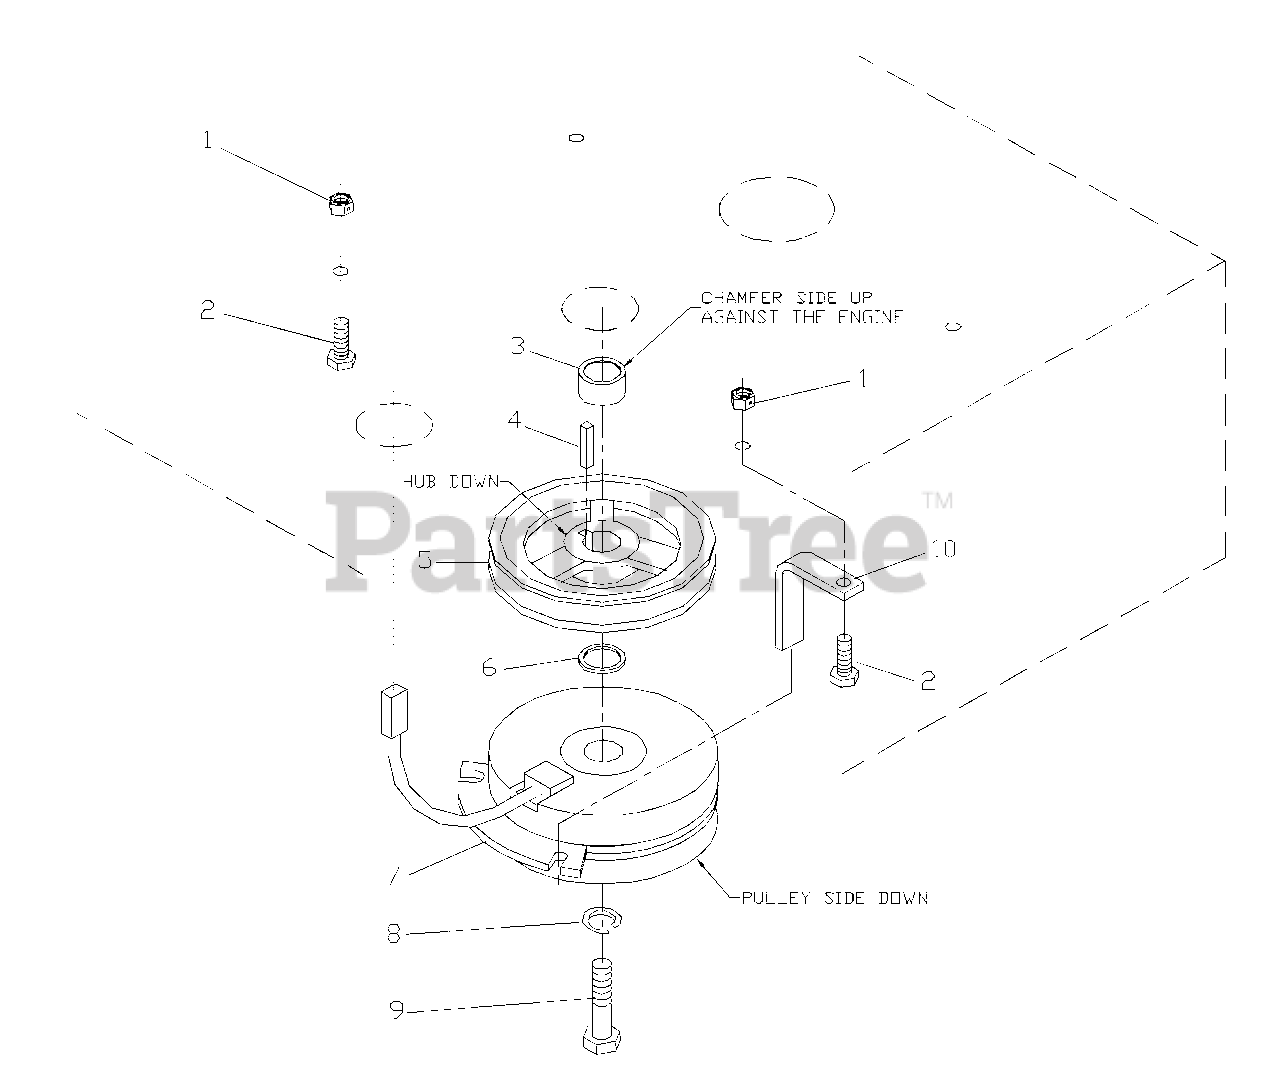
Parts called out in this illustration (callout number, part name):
1	NUT 5/16C CENTERLOCK
2	HCS 5/16C X 1 3/4
4	KEY 1/4 SQ. X 1 1/8
6	10GA. MACHINERY BUSHING
7	ELECTRIC CLUTCH
8	7/16 LOCKWASHER
9	HCS 7/16F X 2 1/2
10	CLUTCH TIE DOWN
